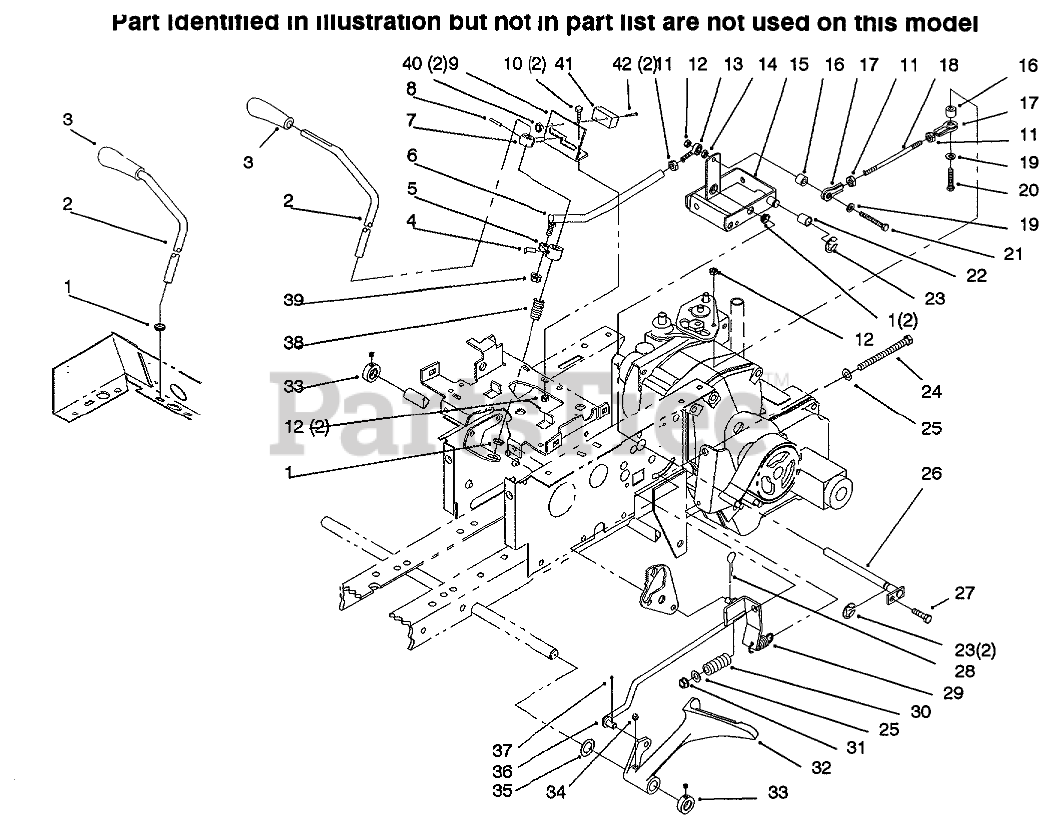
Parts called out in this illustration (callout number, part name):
1	NYLINER BUSHING
2	ROD-MOTION CONTROL
3	Knob
4	SPIROL PIN 7/32X7/8
5	ARM-CONTROL
6	ASSY-ROD & BALL JOINT
7	GUIDE-CONTROL
8	PIN-SPECIAL
9	Bracket-Control
10	SCREW-HH
11	NUT-JAM
12	NUT-LOCK, NI
13	ROD END, 1/4-28
14	NUT-HEX
15	Cam Comtrol
16	Spacer
17	ASSY ROD END
18	ROD-CONTROL
19	WASHER-FLAT
20	SCREW-HH
21	HHCS 1/4X2.25 FULL T
22	BEARING-CAM RETURN
23	RING-RETAINING, EXTERNAL
24	SCREW-HH
25	WASHER-FLAT
26	ASSY-ROD CAM PIVOT
27	Bolt
28	PIN-HAIR
29	SPRING
30	SPRING-COMPRESSION
31	NUT-LOCK, NI
32	Pedal-Brake
33	COLLAR
33:1	SCREW-HSH
34	FITTING-GREASE
35	WASHER
36	ASY BRAK RD WAR
37	PIN-COTTER
38	SPRING-COMPRESSION
39	NUT-LOCK
40	NUT-HEX
41	SWITCH - CLUTCH
42	SCREW-PPH
